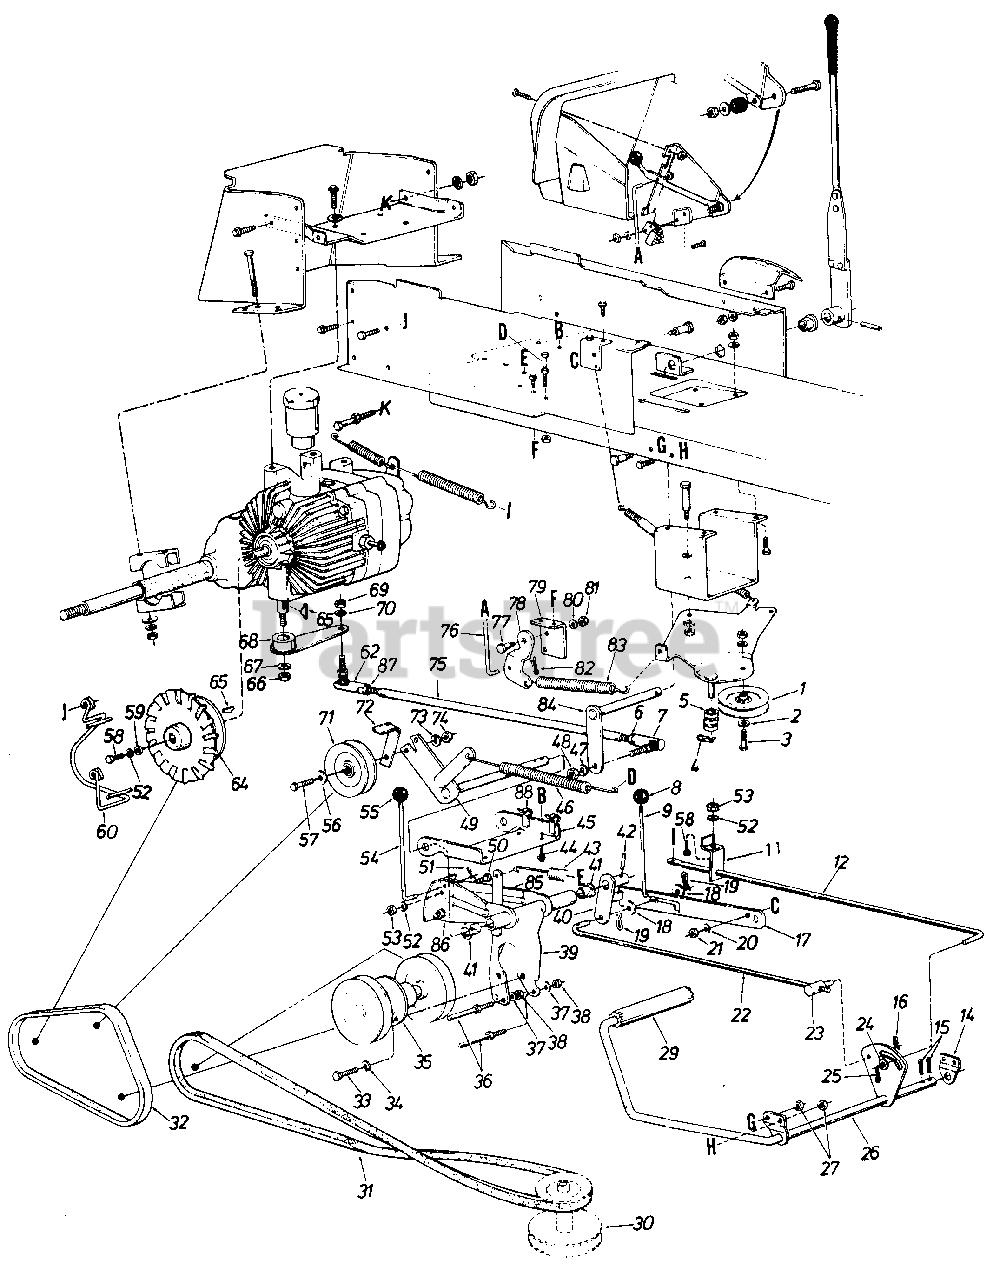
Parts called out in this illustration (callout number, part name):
1	4" Dia. "V"-Idler Pulley
2	Fl-Wash. 3/8" I.D.
3	Hex Bolt 3/8-16 x 1.25" Lg.
4	Intern. Cotter Pin 5/16" Dia.
5	Spacer
6	Hex Jam L-Nut 3/8-24 Thd.
7	Ball Joint Ass'y. 3/8-24 Thd.
8	Ball Knob
9	Parking Brake Link
11	Brake Rod Hanger
12	Brake Rod
14	Clutch Rod Brg. Brkt.
15	Cotter Pin 1/8" Dia. x 1.00" Lg
16	Hairpin Cotter 1/2" Dia.
17	Parking Brake Cam
18	Fl-Wash. .406 I.D. x 1.00" O.D. x .030
19	Hairpin Cotter 1/2" Dia.
20	L-Wash. 5/16" I.D.
21	Hex Nut 5/16-18 Thd.
22	Brake Cam Rod
23	Pivot Bushing
24	Fl-Wash. .401" I.D. x .749" O.D. x .057" Thk.
25	Cotter Pin 3132" Dia. x .75" Lg.
26	Clutch Brake Pedal Ass'y.
27	Hex L-Nut 3/8-16 Thd.
29	Foot Pad
30	Two-Step Engine Pulley 4.75" and 5.56"
31	"V"-Belt 1/2" x 59" Lg.
32	"V"-Belt 1/2" x 37" Lg.
33	Hex Sems Bolt 5/16-18 x .75" Lg.
34	L-Wash. 5/16" I.D.
35	Jack Shaft Ass'y.
36	Stud 3/8-16 x 3.62" Lg.
37	L-Wash. 3/8" I.D.
38	Hex Nut 3/8-16 Thd.
39	Jack Shaft Mtg. Brkt. Ass'y.
40	Clutch Idler Horn Ass'y.
41	Nyliner 5/8" I.D. x .88" Lg.
42	Spring Pin Spiral 1/4" Dia. x 1.5" Lg.
43	IExt. Spring
44	IHex Wash. Hd. Self-Tap Scr. 1/4-20 x .50" Lg.
45	Idler Mtg. Brkt.
46	Ext. Spring
47	L-Wash. 3/8" I.D.
48	Hex Nut 3/8-24 Thd.
49	Clutch Brkt. Ass'y.
50	Hex Bolt 1/4-20 x .50" Lg.
51	Internal Cotter Pin 5/16" Dia. Rod
52	L-Wash. 1/4" I.D.
53	Hex Nut 1/4-20 Thd.
54	Relief Valve Lockout Rod
55	Ball Knob
56	Fl-Wash. 3/8" I.D.
57	Hex Bolt 3/8-16 x 1.25" Lg.
58	Hex Bolt 1/4-20 x .62" Lg.
59	Fl-Washer
60	Belt Guard Ass'y.
62	Ball Joint Ass'y. 3/8-24 L.H. Thd.
64	Transaxle Pulley w/Fan
65	Hi-Pro Key 1/8" x 1/2" Dia.
66	Hex Nut 3/8-16 Thd.
67	L-Wash. 3/8" I.D.
68	Pintle Arm Ass'y.
69	Hex Nut 3/8-24 Thd.
70	L-Wash. 3/8" I.D.
71	4" "V"-Idler Pulley
74	Hex Nut 3/8-16 Thd.
75	Speed Control Rod
76	Deck Control Rod
77	Shld. Scr. .437" Dia. x .162" Lg. (5/16-18)
78	Deck Control Pivot Brkt.
79	Parking Brake Cam Mtg. Brkt.
80	L-Wash. 5/16" I.D.
81	Hex Nut 5/16-18 Thd.
82	Internal Cotter Pin 5/16" Rod
83	Extension Spring
84	Speed Control Shaft Ass'y.
85	Relief Valve Cam L.H.
86	Relief Valve Cam R.H.
87	Hex Jam L-Nut 3/8-24 L.H. Thd.
88	Plastic Hose Clamp
